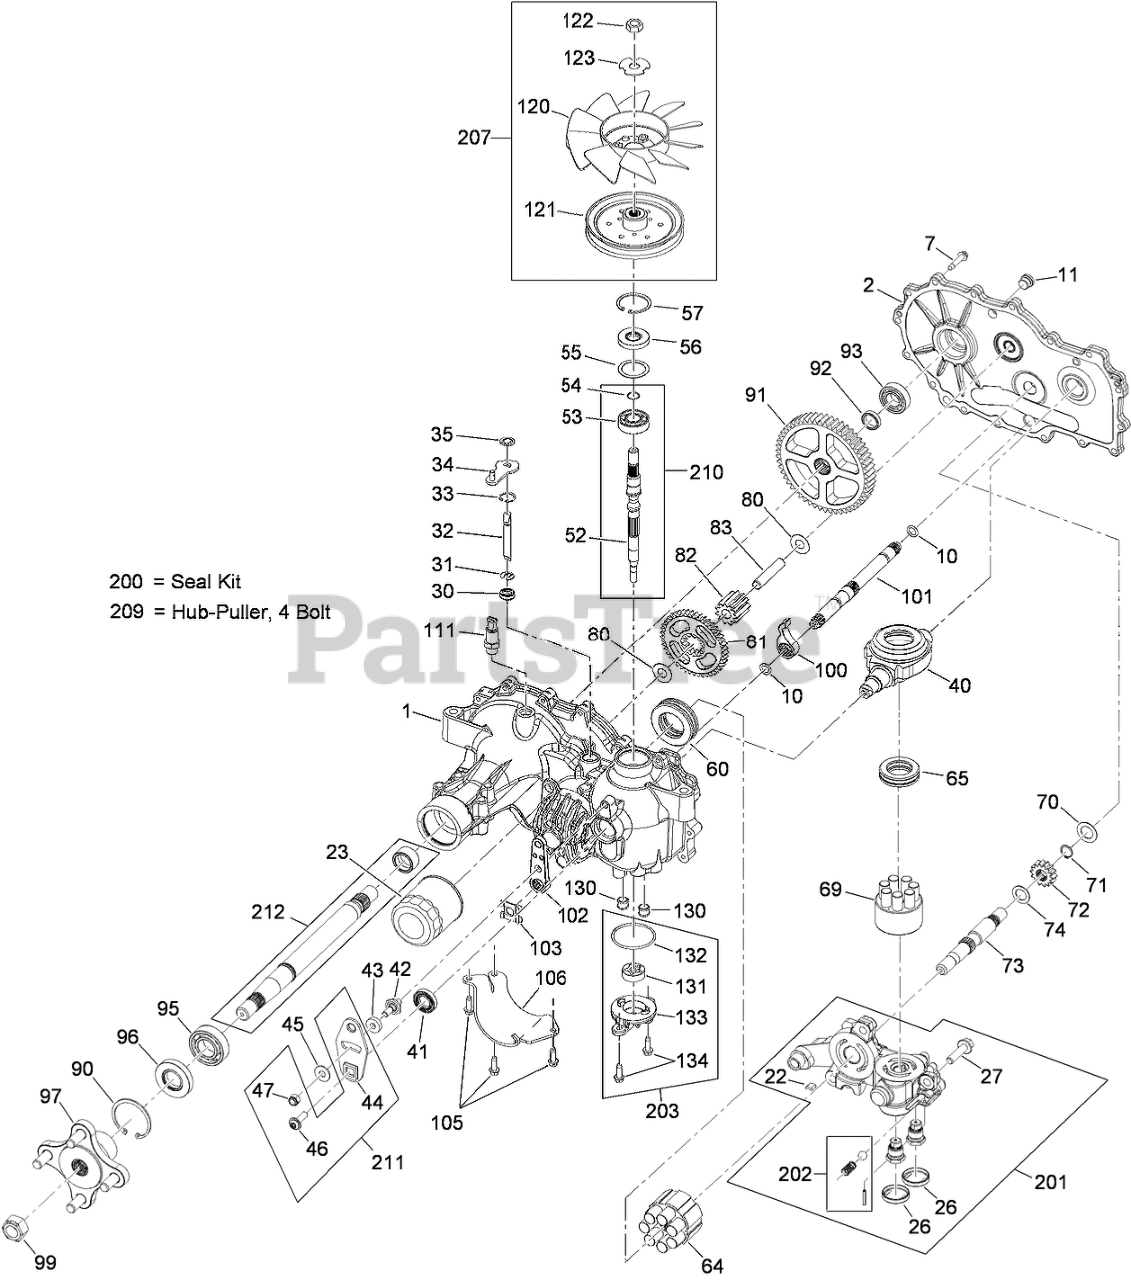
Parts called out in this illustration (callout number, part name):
1	RH MAIN HOUSING KIT
2	RH HOUSING SIDE KIT
7	SCREW-HHF
10	O-RING
11	PLUG-THREAD, STRAIGHT
22	PLATE-BYPASS
23	ELEMENT-OIL FILTER, HYD
26	SEAL-PLUG
27	SCREW-HFHC
30	SEAL-LIP
31	RING-RETAINING, EXTERNAL
32	ROD-BYPASS
33	RING-RETAINING, INTERNAL
34	ARM-BYPASS
35	RING-RETAINING, EXTERNAL
40	SWASHPLATE-TRUNNION
41	SEAL-LIP
43	PUCK-FRICTION
44	ARM-CONTROL
45	WASHER
52	SHAFT-INPUT
53	BEARING-BALL
54	RING-RETAINING
55	SPACER
56	SEAL-LIP
57	RING-RETAINING
60	BEARING-THRUST
64	MOTOR CYLINDER BLOCK KIT
65	BEARING-THRUST
69	PUMP BLOCK ASM
70	WASHER-FLAT
71	RING-RETAINING
72	GEAR-14T
73	SHAFT-MOTOR
74	WASHER
80	WASHER
81	GEAR-45T
82	GEAR-11T
83	PIN-JACKSHAFT
90	RING-RETAINING
91	GEAR-54T
92	SPACER
93	BEARING-BALL
95	BEARING-BALL
97	HUB KIT
100	PAWL-BRAKE
101	SHAFT-BRAKE
102	HANDLE-BRAKE
103	CLIP-RETAINING
106	GUARD-FILTER, LH
111	ADAPTER-STRAIGHT
120	FAN-7.0
121	PULLEY-5.0 INCH
122	NUT-HEX
123	WASHER-SLOTTED
130	TUBE-CONNECTING
131	GEROTOR ASM
132	O RING-SEAL
133	COVER-CHARGE PUMP
200	SEAL KIT
201	RH CENTER SECTION KIT
202	CHARGE RELIEF KIT
203	CHARGE KIT
207	FAN AND PULLEY KIT
209	PULLER-HUB, 4 BOLT
210	INPUT SHAFT KIT
211	CONTROL ARM KIT
212	AXLE SHAFT KIT
